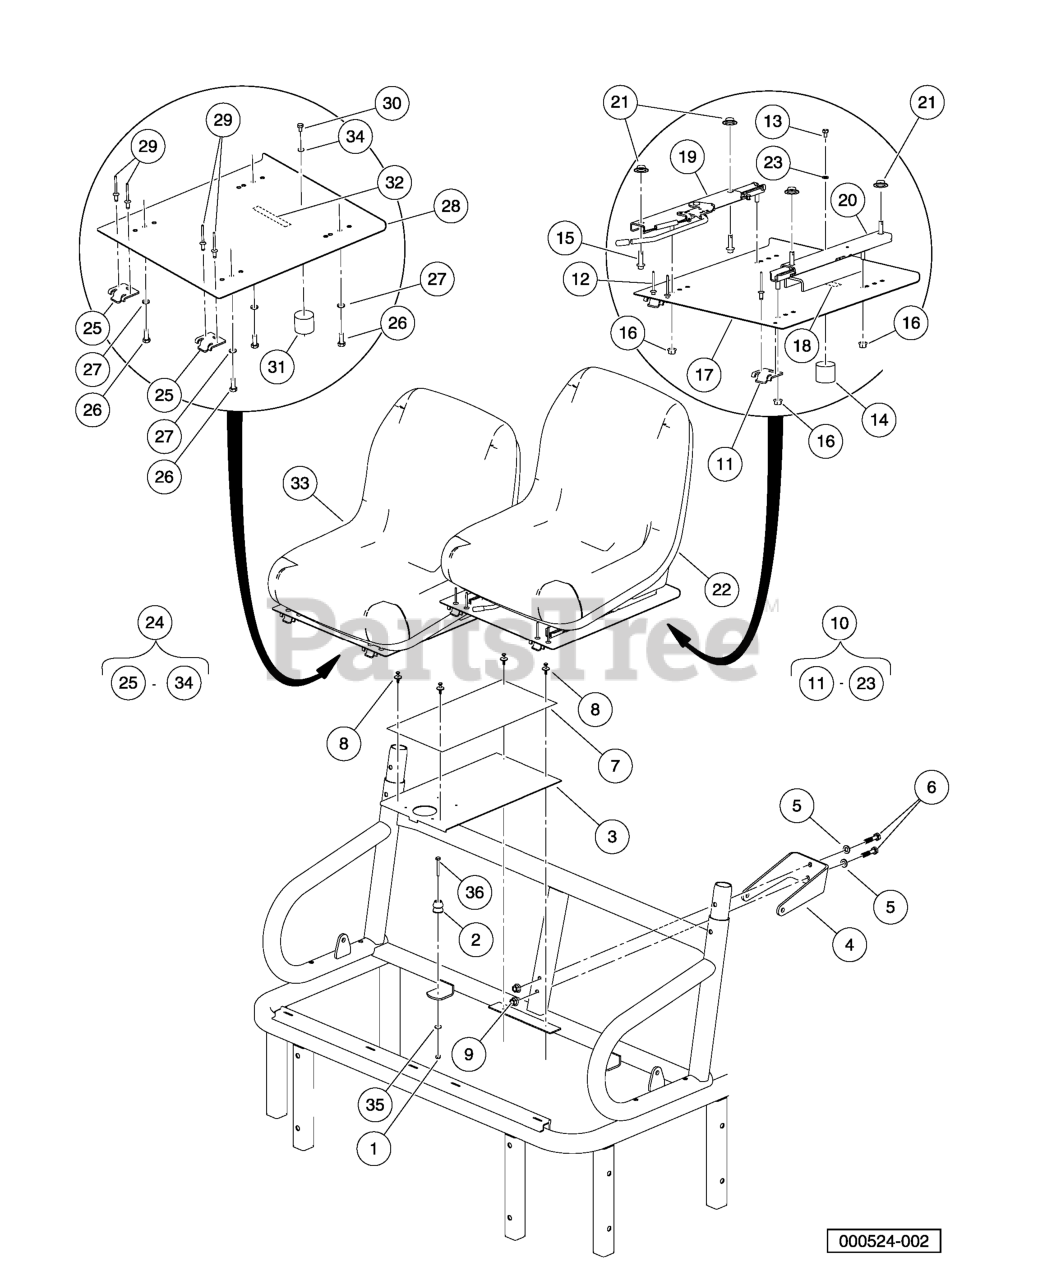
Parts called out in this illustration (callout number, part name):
1	LOCKNUT, M6-1.00 NYLON INSERT
2	SEAT HOLDER BASE
3	PAN, CENTER, CLOSEOUT
4	BRKT, SEATBELT, BOLT-ON
5	WASHER, HARD, M10, ZN-NI/BLK
6	BOLT, M10 X 45, ZN-NI/BLK
7	COVER, CENTER CONSOLE
8	SCREW, TUFLOK PANEL, 1/4
9	NUT, FLANGED, M10 X 1.5, BLACK
10	Asm, Bracket Seat, Adj, Blk
11	HINGE PLATE
12	RIVET, 1/4 X .438 BLIND
13	SCREW, 6M-1.00 X 10MM HEX HEAD
14	SEAT HOLDER CUP
15	BOLT - FLANGED HD, M8 X 30.0
16	NUT FLG, M8 X 1.25 MECH DEF
17	PAN, SEAT, DRIVER ASM
18	DECAL, WARNING HOT SURFACE
19	ADJUSTER, FORE/AFT
20	ADJUSTER, SLIDER
21	WASHER, BELL
22	SEAT, BUCKET, BLACK
23	LOCKWASHER, 1/4 HELICAL SPLIT
24	Asm, Bracket Seat, Passenger, Blk
25	HINGE PLATE
26	SCREW, M8-125 X 22 HEX GR.8.8
28	PAN, SEAT - PASSENGER
29	RIVET, 1/4 X .438 BLIND
30	SCREW, 6M-1.00 X 10MM HEX HEAD
31	SEAT HOLDER CUP
32	DECAL, WARNING HOT SURFACE
33	SEAT, BUCKET, BLACK
34	LOCKWASHER, 1/4 HELICAL SPLIT
35	WASHER 1/4 FLAT
36	BOLT, M6 X 1 X 45
